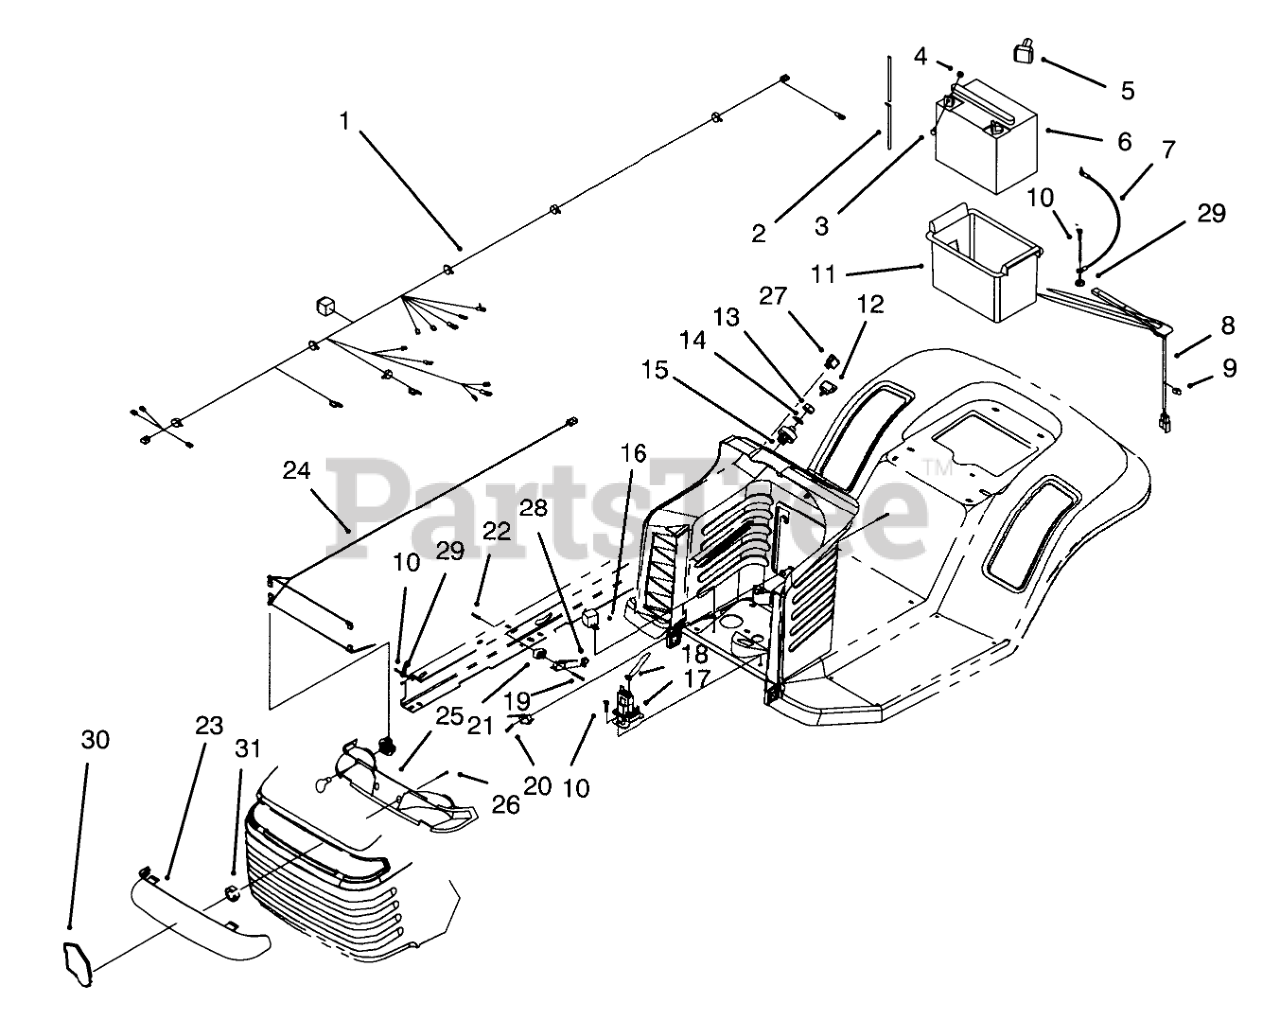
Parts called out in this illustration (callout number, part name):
1	Harness-Wire
2	TUBE-BATT DRAIN/80-2600
3	SCREW-HH
4	NUT-WING
5	BOOT-TERMINAL
6	Battery
7	WIRE ASM
8	SWITCH-SEAT
9	CLIP-RETAINER, WIRE
10	SCREW-HWH
11	BOX-BATTERY
12	KEY-IGNITION
13	NUT-HH
14	WASHER-TOOTH, INTERNAL
15	Key Switch ASM
16	RELAY
17	SOLENOID
18	NUT-KEPS
19	Screw
20	SWITCH-MICRO
21	SPACER
22	NUT-SPEED
23	LENS-HEADLIGHT
24	HARNESS-WIRE, LIGHTS
25	HEADLIGHT REFLECTOR ASM
27	MICROSWITCH ROCKER SWCH
28	Seal-Plunger
29	WASHER-LOCK/EXT
30	EMBLEM-GRILLE WHEELHORSE
